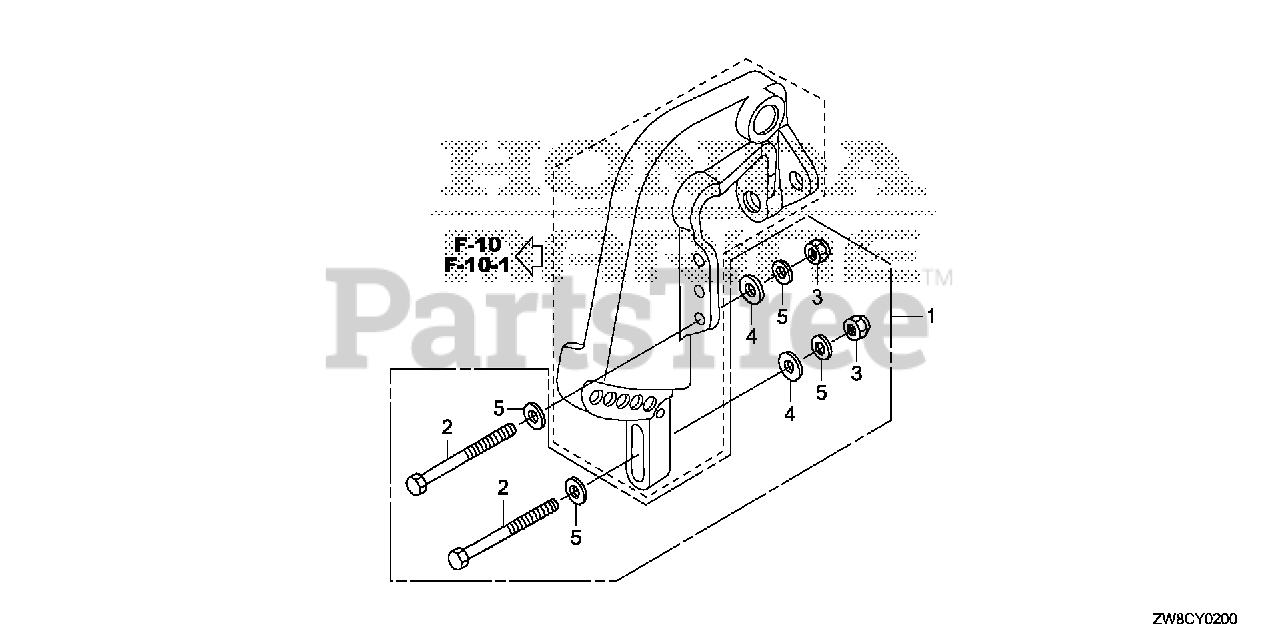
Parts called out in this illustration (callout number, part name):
1	INSTALLATION KIT, OUTBOARD
2	BOLT, HEX. (10X100)
3	NUT, SELF-LOCK (10MM)
4	WASHER, PLAIN (10MM)
5	WASHER, PLAIN (10MM)
